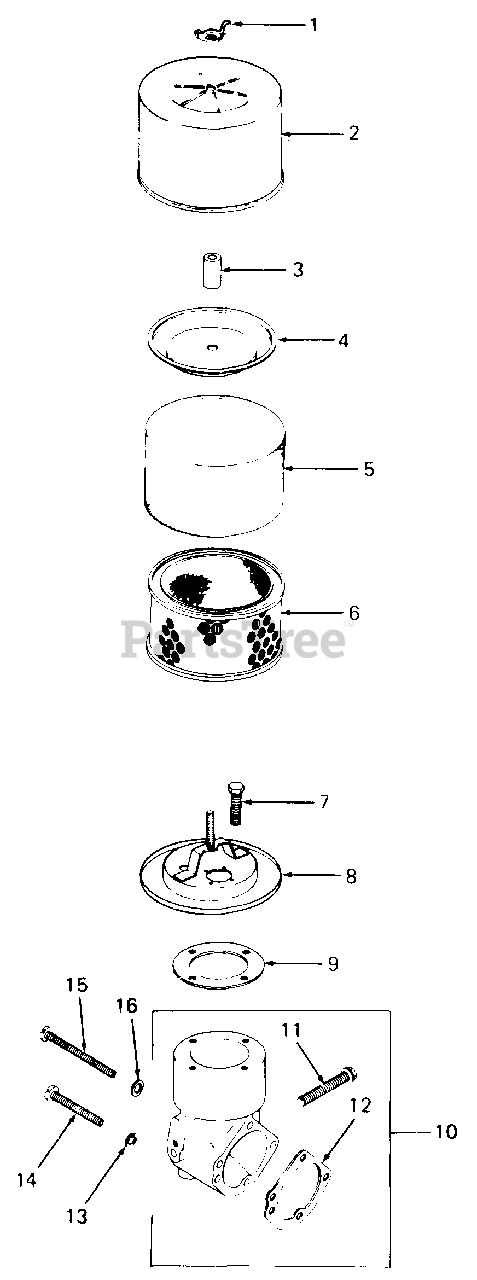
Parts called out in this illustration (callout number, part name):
1	Nut, Wing, 1/4-20
2	Cover, Air Cleaner
3	Seal, Element Cover
4	Cover, Air Cleaner Element
5	Precleaner
6	Element
7	Screw, Sltd Hex Wash Hd, #10-32 x .56 Lg
8	Base, Air Cleaner
9	Gasket, Air Cleaner
10	Kit, Elbow
11	Screw, Hex Cap, 1/4-20 x .62 Lg
12	Gasket, Air Intake Elbow
13	Washer, I.T. #10
14	Screw, Sltd Pan Hd, #10-32 x 1.5 Lg
15	Screw, Sltd Pan Hd, #10-32 x 2.25 Lg
16	Washer, Plain, #10
